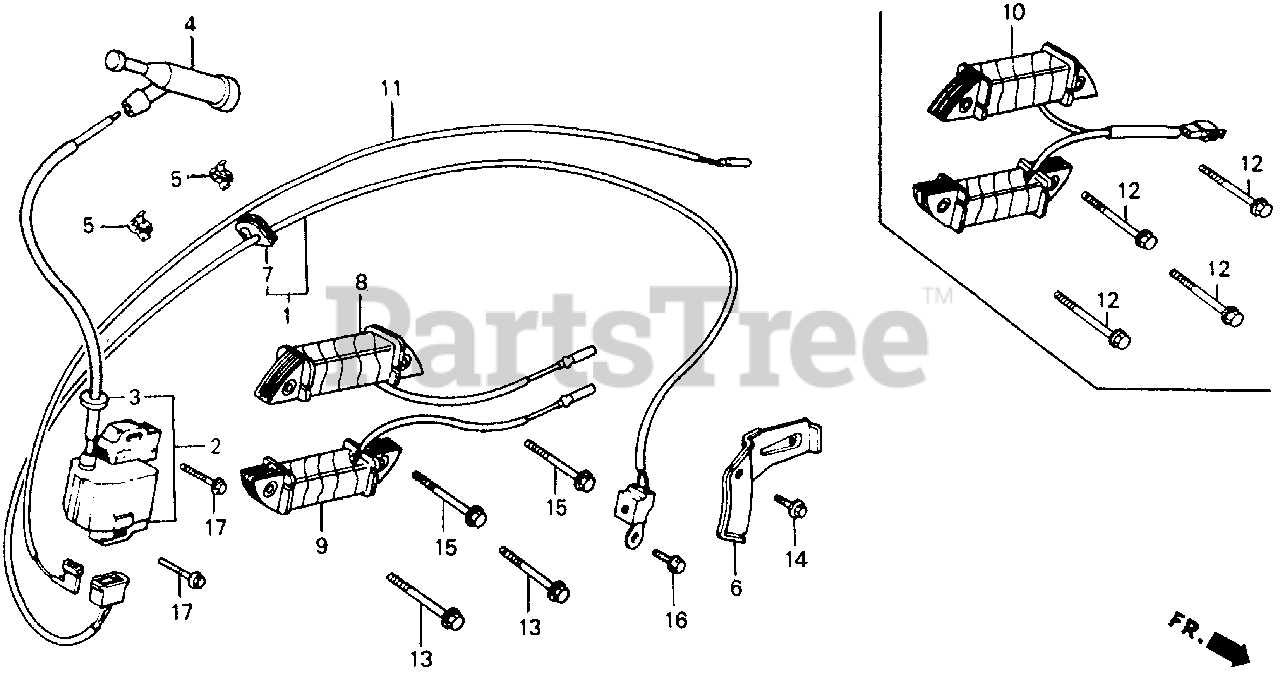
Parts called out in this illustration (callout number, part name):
1	COIL, PULSER
2	COIL ASSY., IGNITION
3	GROMMET, IGNITION WIRE
4	CAP ASSY., NOISE SUPPRESSOR
5	CLIP, IGNITION WIRE (8MM)
7	GROMMET, PULSER WIRE
11	WIRE, STOP SWITCH
16	BOLT, FLANGE (6X14)
17	BOLT, FLANGE (6X28)
